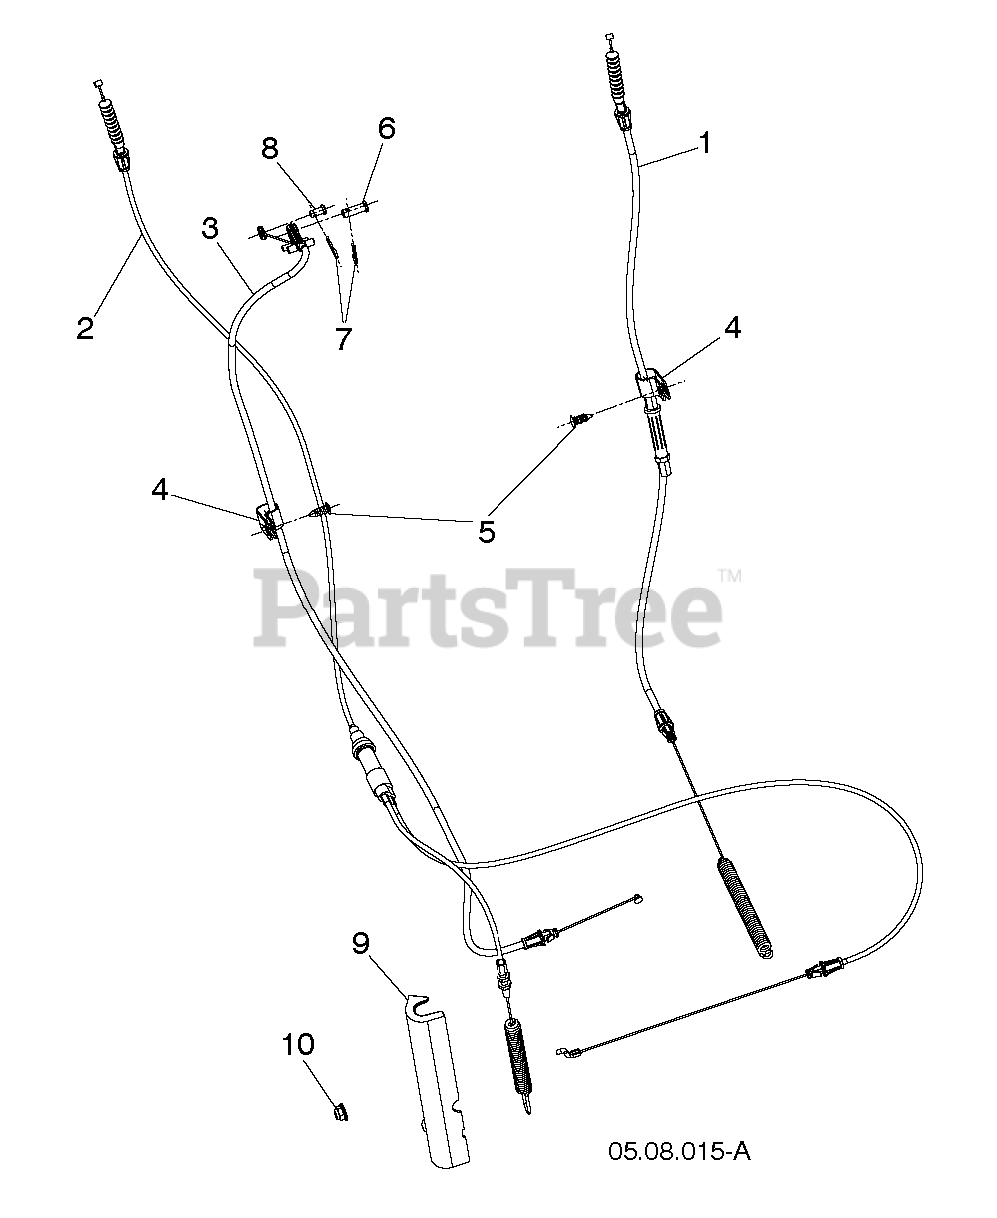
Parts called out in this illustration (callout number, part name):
1	CABLE DRIVE WITH ADJUSTER
2	CABLE IMPELLER
3	CABLE.CONTROL.SPEED.DSST.OPP
4	CLIP.CABLE.BLK
5	FASTENER.PUSH.O.250X0.783
6	PIN CLEVIS 5/16X.875
7	HAIRPIN.SOFT.ZINC.059X1.125
8	PIN CLEVIS .25 X .31
9	COVER AUGER CABLE
10	NUTNYLOK.FLRANGE.5/16-18
